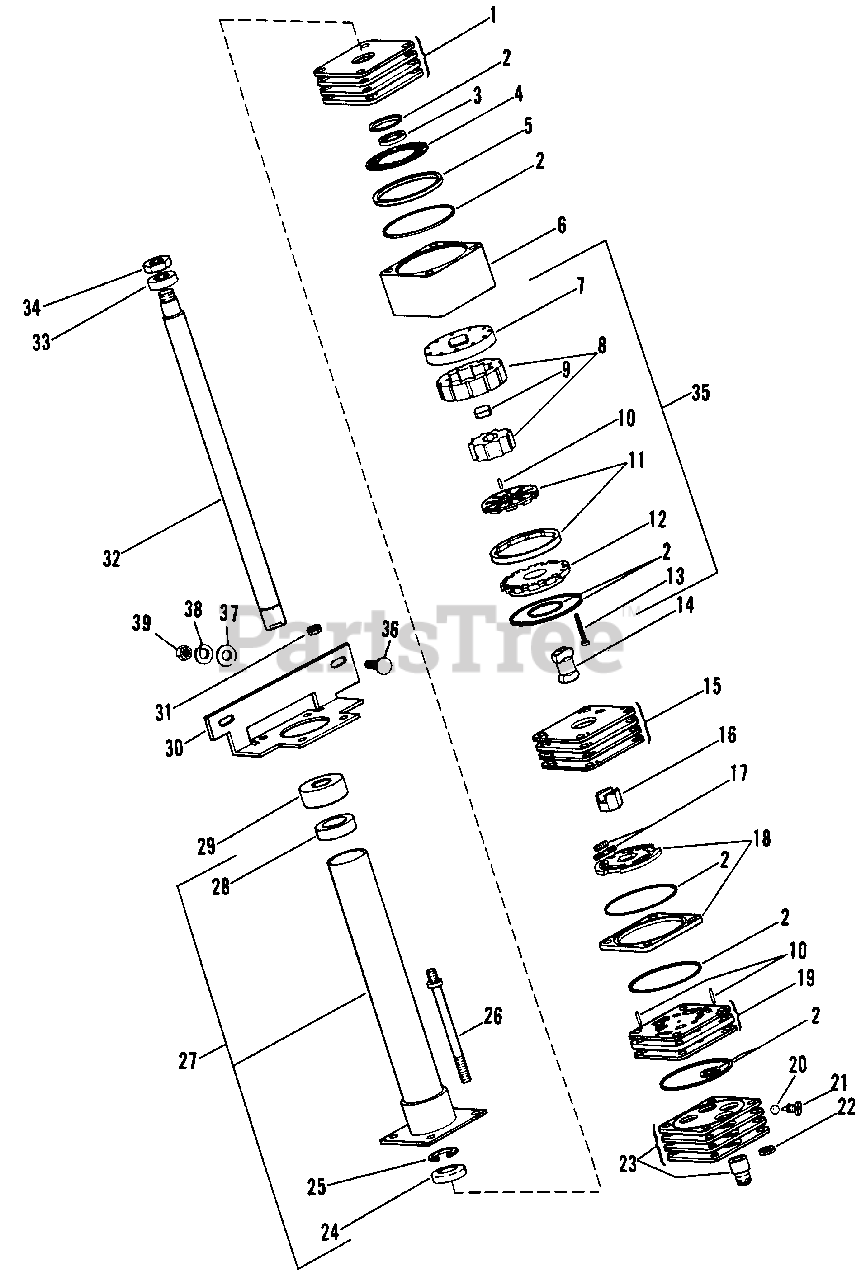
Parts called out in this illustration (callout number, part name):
1	Plate, Upper Cover
2	Assembly, Seal Service
3	Spacer, Seal
4	Bearing, Thrust
5	Spacer
6	Ring, Metering
7	Plate, Drive
8	Rotor
9	Spacer
10	Assembly, Needle Roller Service
11	Assembly, Commutator and Ring
12	Cover, Commutator
13	Screw, Special
14	Link, Drive
15	Manifold, Isolation
16	Drive, Hex
17	Assembly, Spring Service
18	Assembly, Valve and Ring
19	Manifold, Port
20	Ball, Steel
21	Assembly, Plug and Ring
22	Nut, Lock 5/16-24
23	Assembly, Port Cover and Check Valve
24	Washer
25	Ring, Retaining
26	Stud, Special
27	Assembly, Upper Cover and Jacket Tube
28	Bearing, Column
29	Cap
30	Bracket
31	Lock Nut, 5/16-24 Gr. C
32	Shaft, Input
33	Cover, Dust
34	Nut, Lock 5/8-18 Jam
35	Assembly, Metering
36	Bolt, Carriage 5/16-18 x 1.00
37	Washer, Flat .406 x .812 x .065
38	Washer, Lock 5/16 SP
39	Nut, Hex 5/16-18
40	Tie Cable
